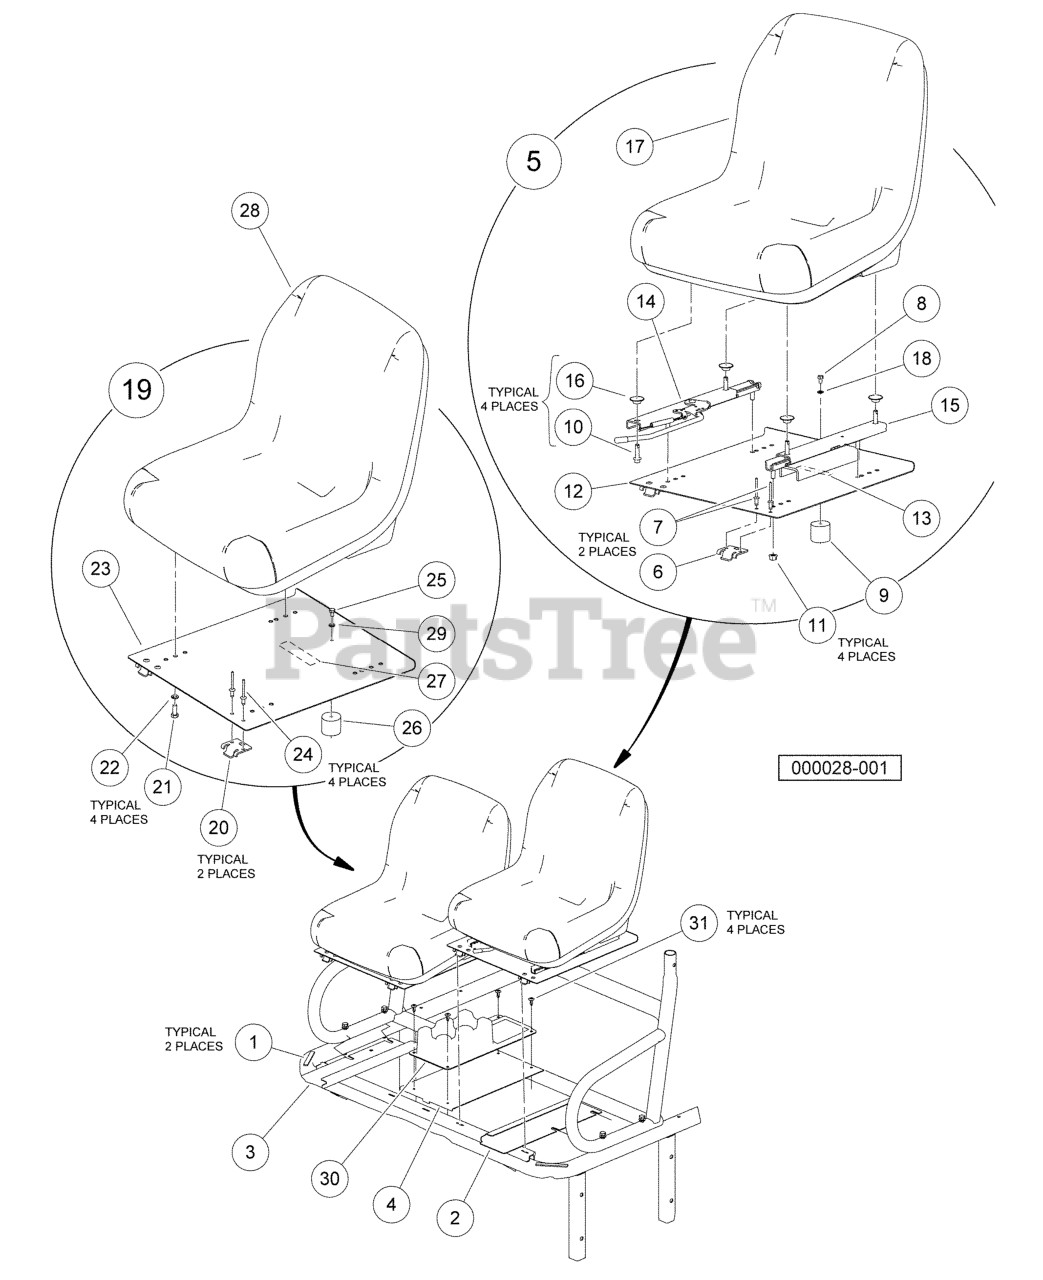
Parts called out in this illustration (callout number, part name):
1	BOX INS.BULK
2	CLOSEOUT, DRIVER SIDE
3	CLOSEOUT, PASSENGER SIDE
4	PAN, CENTER, CLOSEOUT
5	ASM, BUCKET SEAT ADJUSTABLE
6	HINGE PLATE
7	RIVET, 1/4 X .438 BLIND
8	SCREW, 6M-1.00 X 10MM HEX HEAD
9	SEAT HOLDER CUP
10	BOLT - FLANGED HD, M8 X 30.0
11	NUT FLG, M8 X 1.25 MECH DEF
12	PAN, SEAT, DRIVER ASM
13	DECAL, WARNING HOT SURFACE
14	ADJUSTER, FORE/AFT
15	ADJUSTER, SLIDER
16	WASHER, BELL
17	SEAT, BUCKET, GRAY
18	LOCKWASHER, 1/4 HELICAL SPLIT
19	Assembly, Bucket Seat w/Spacers
20	HINGE PLATE
21	SCREW, M8-125 X 22 HEX GR.8.8
23	PAN, SEAT - PASSENGER
24	RIVET, 1/4 X .438 BLIND
25	SCREW, 6M-1.00 X 10MM HEX HEAD
26	SEAT HOLDER CUP
27	DECAL, WARNING HOT SURFACE
28	SEAT, BUCKET, GRAY
29	LOCKWASHER, 1/4 HELICAL SPLIT
30	CONSOLE, CENTER, DRINK HLDR
31	SCREW, TUFLOK PANEL, 1/4
